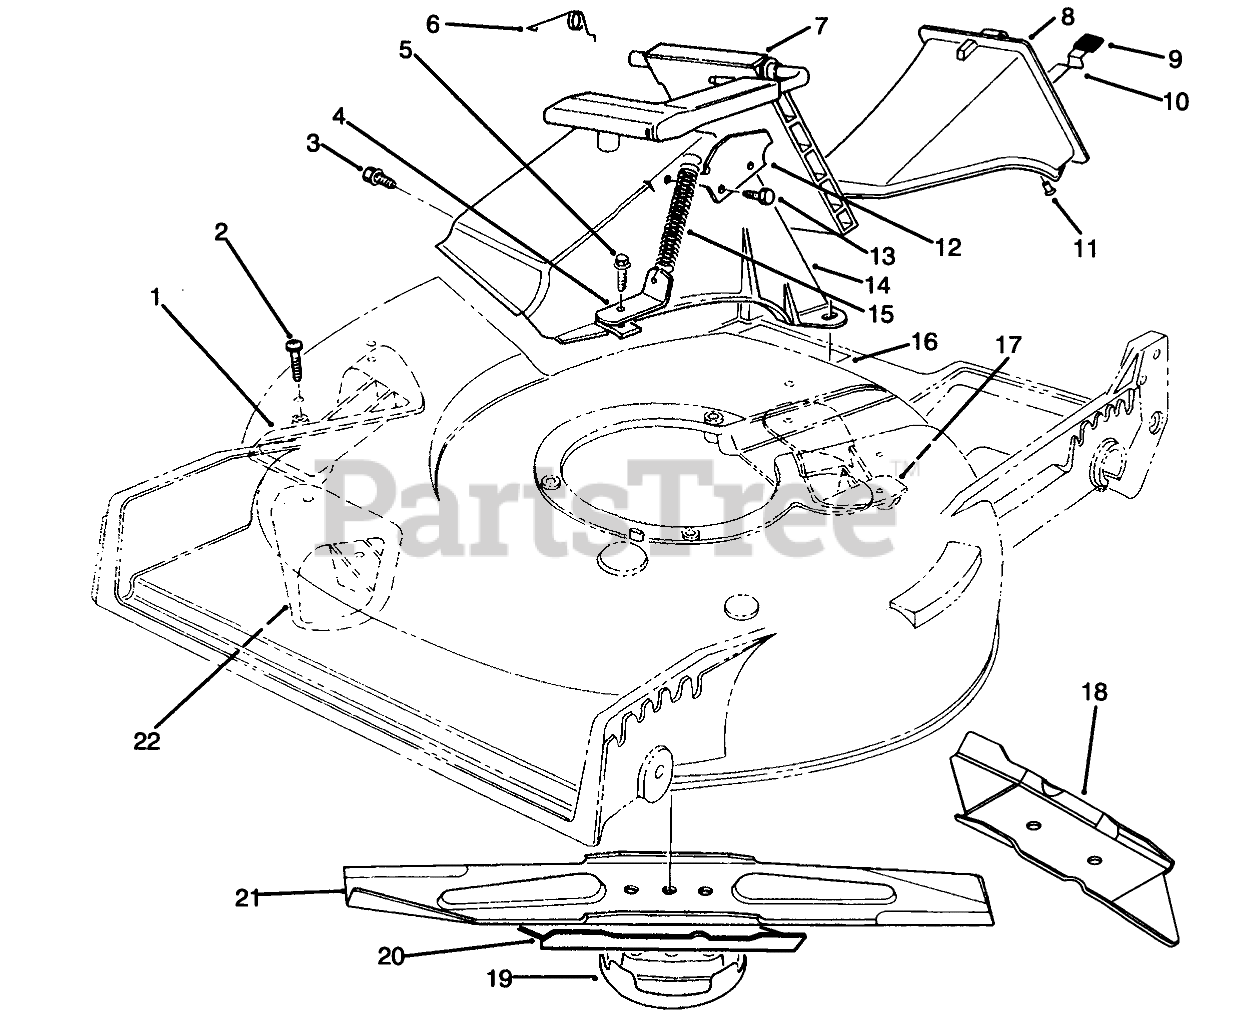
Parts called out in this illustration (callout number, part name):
1	KICKER-RH
2	SCREW-PPH
3	SCREW AND WASHER ASM
4	BRACKET-SPRING
5	SCREW-HWH
6	RETAINER-DOOR
7	DOOR ASSEMBLY
8	Plug Assembly (Incl. Ref. #9-11)
9	GRIP-LATCH
10	LATCH-PLUG, DISCHARGE
11	RIVET-HEAD, FLAT
12	DOOR LATCH PLATE
13	SCREW-PLASTITE
14	DISCHARGE TUNNEL
15	SPRING-DOOR
16	DECAL - CAUTION
17	KICKER-REAR
18	Accelerator
19	CUP-SCALP, ANTI
20	Accelerator
21	Blade
22	KICKER-FRONT
